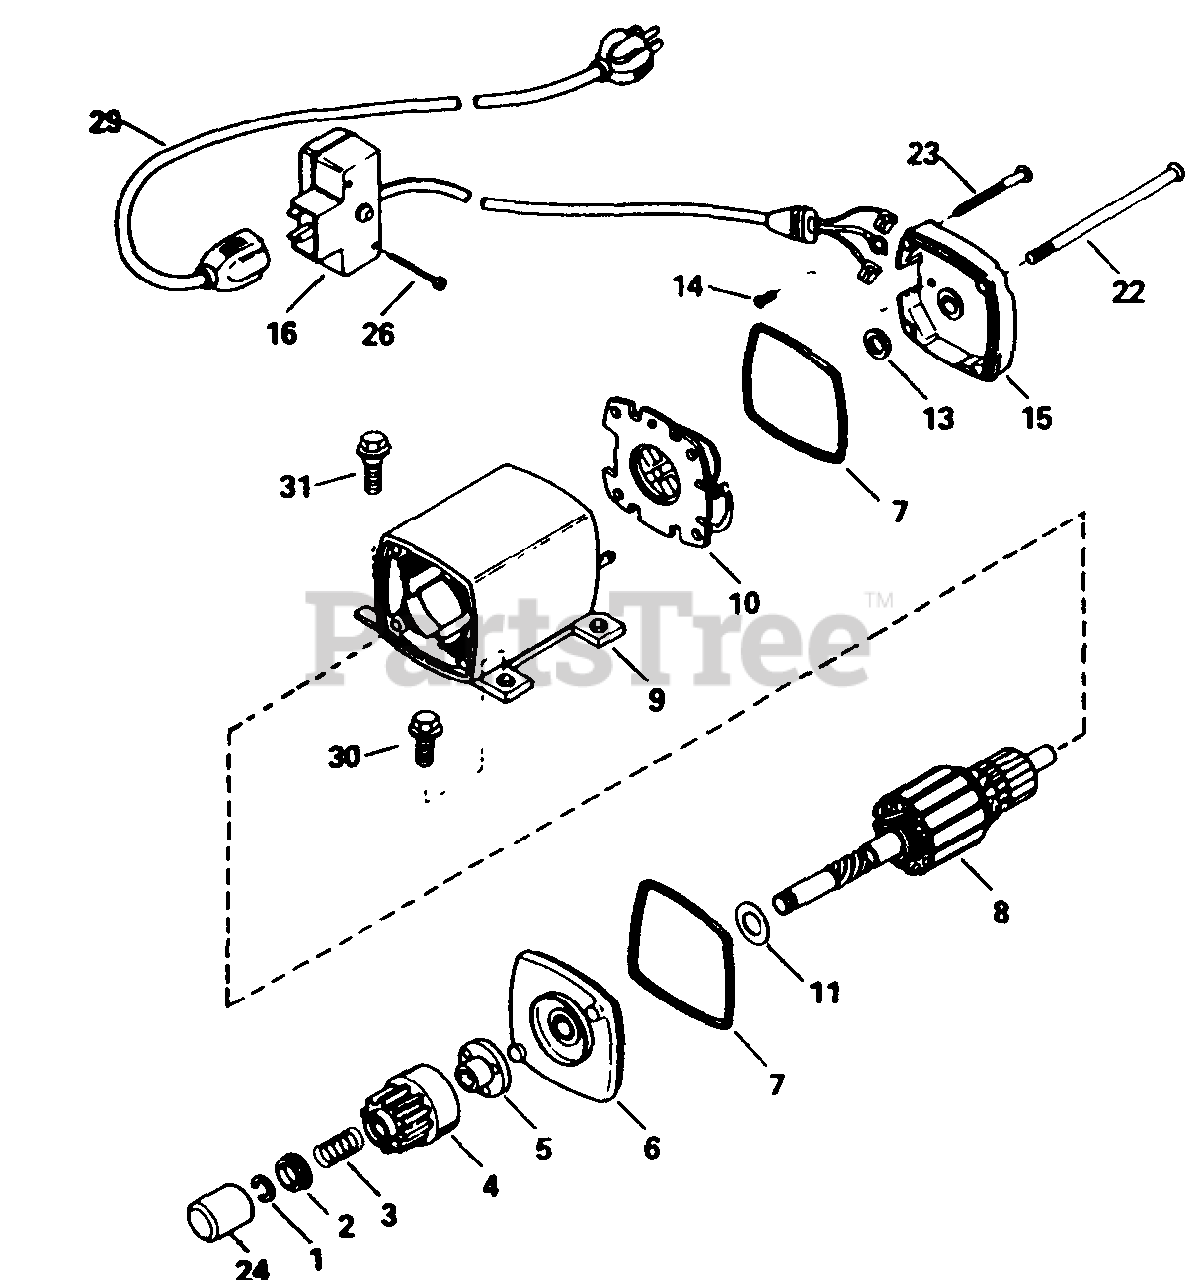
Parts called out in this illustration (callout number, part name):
1	Ring, Retainer
2	Retainer, Spring
3	Spring, Anti-drift
5	Nut and Retainer
6	Cap Ass'y., Drive End
9	Housing Ass'y.
10	Card Ass'y., Brush
11	Washer, Thrust
13	Washer, Thrust
14	Screw, Ground
15	Cap Ass'y., Commutator End
16	Box Ass'y., Switch
22	Bolt, Case
23	Screw, Grounding
24	Cover, Dust
26	Screw, Hex Hd. Self-Tap, 6-32 x 2-1/2
29	Cord, Extension (10'6")
30	Screw, Fil. Hd Sems, 1/4-20 x 9/16
31	Screw, Hex Hd. Shoulder, 1/4-20 x 1/2
